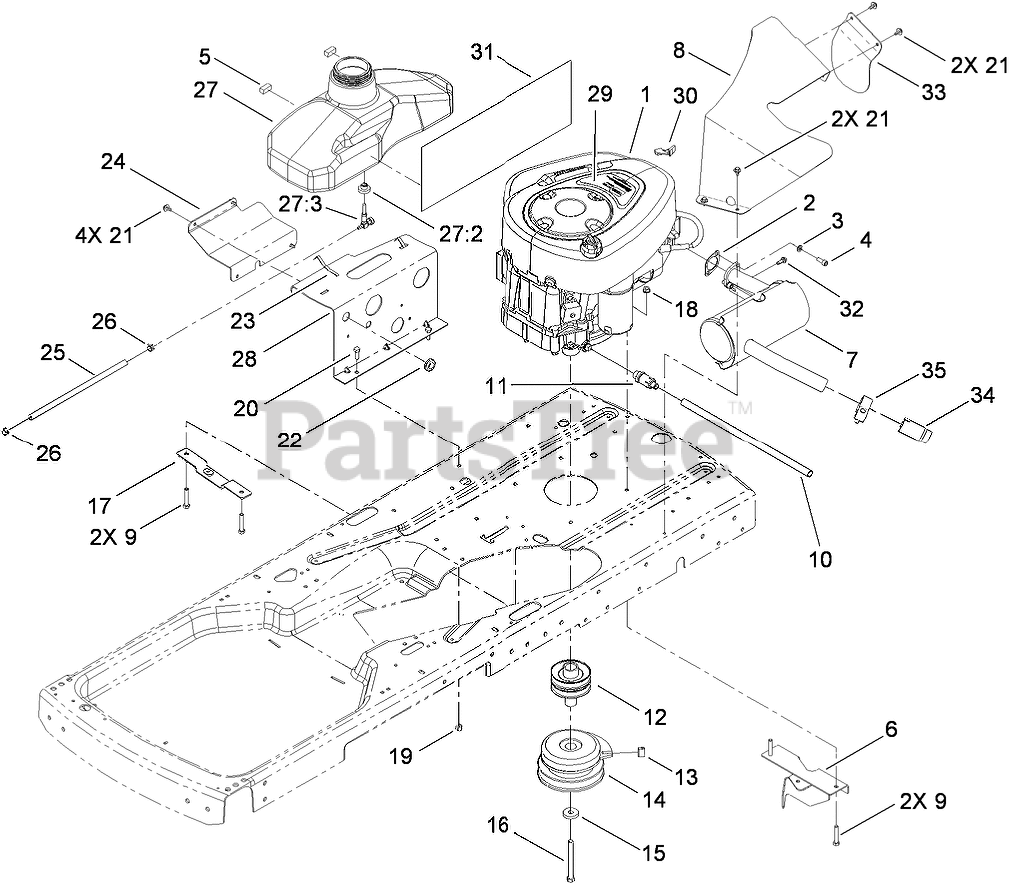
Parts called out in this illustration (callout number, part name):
2	GASKET-EXHAUST
3	WASHER-LOCK
4	SCREW-HSH
5	FOAM-SWITCH, SEAT
6	BRACKET-PIVOT
7	MUFFLER
8	SHIELD-CLIPPING
9	SCREW-HH
10	TUBE-DRAIN, OIL
11	VALVE-DRAIN, OIL
12	PULLEY-ENGINE
13	BUMPER
14	CLUTCH-ELECTRIC
15	WASHER
16	SCREW-HH
17	PLATE-MOUNT, IDLER
18	NUT-HF
19	NUT-LOCK, NI
20	SCREW-HH
21	SCREW-HHFTF
22	GROMMET
23	SPRING
24	PLATE-SUPPORT
25	HOSE-FUEL
26	CLAMP-HOSE
27	GAS TANK ASM
27:2	BUSHING
27:3	VALVE-FUEL
28	PLATE-TANK
29	DECAL-ENGINE
30	REDUCER-THROTTLE, RPM
31	FOIL-SHIELD, HEAT
32	SCREW-HWH, THREAD ROLL
33	SHIELD-DEFLECTOR, HEAT
34	ARRESTER-SPARK
35	CLAMP-MUFFLER
